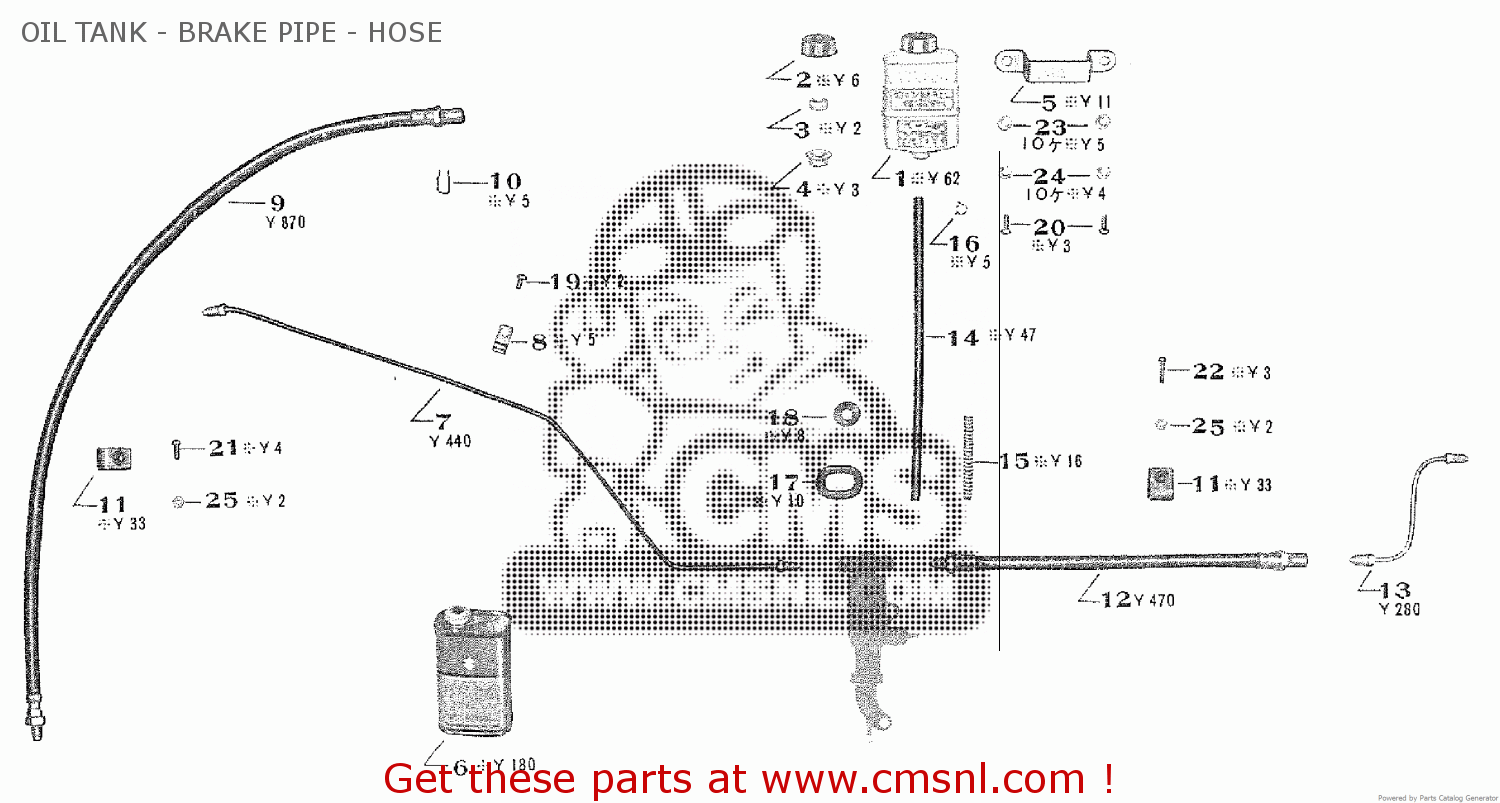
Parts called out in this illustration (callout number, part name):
1	BRAKE OIL TANK ASSY.
2	OIL TANK MAIN CAP
3	OIL TANK SUB CAP UPPER
4	OIL TANK SUB CAP LOWER
5	OIL TANK SET BAND
6	BRAKE OIL
7	FRONT BRAKE PIPE COMP.
8	FRONT BRAKE PIPE SET CLIP
9	FRONT BRAKE HOSE COMP.
10	CUP RING SET CLIP
11	BRAKE HOSE SET CLIP
12	REAR BRAKE HOSE COMP.
13	REAR BRAKE PIPE COMP.
14	RUBBER PIPE
15	RUBBER PIPE COIL
16	RUBBER PIPE CONNECTING CLIP
17	RUBBER PIPE BUSH
18	RUBBER PIPE BUSH
19	6X10 CROSS SCREW
20	6X14 CROSS SCREW
21	6X14 CROSS SCREW
22	6X20 CROSS SCREW
23	6MM LIGHT PLANE WASHER
24	6MM SPRING WASHER
25	6MM HEXAGON NUT
